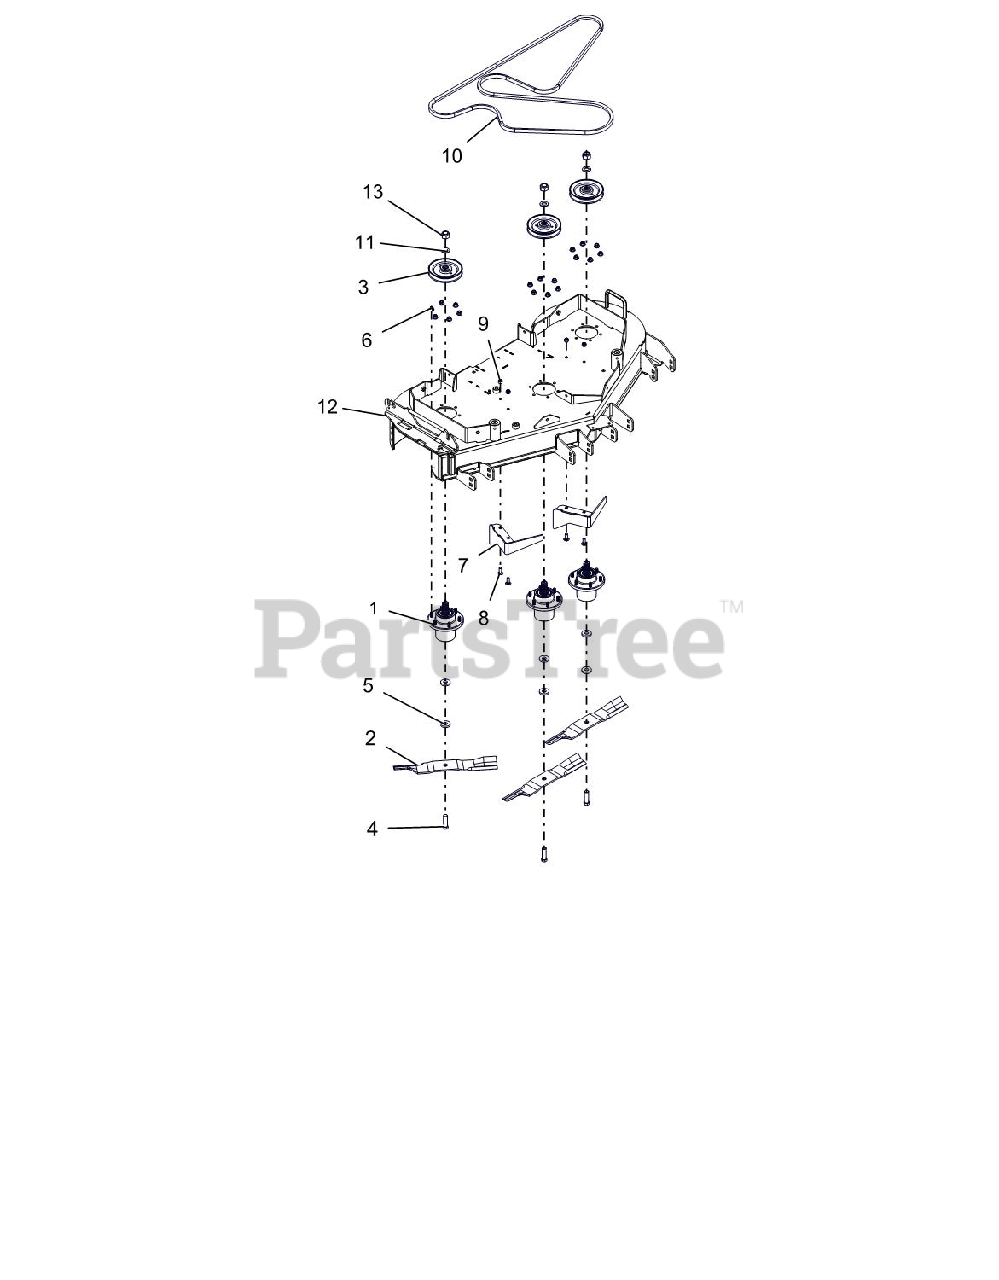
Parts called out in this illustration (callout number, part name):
1	ASSY, SPINDLE HOUSING
2	BLADE, 16.19" MOWER (HI-LIFT)
3	PULLEY, SPINDLE 5.25 X .25
4	BLT, HEX .62-11X2.00 G8 ZCC
5	WSHR,FLT .630X1.50X.25 ZCC
6	NUT,LK-NYL-FLG .38-16 G5ZC120
7	WLDMT, BAFFLE 48
8	BLT,RHSSN .38-16X1.00 G5 ZC120
9	NUT,NYL .38-16 G5 ZCC
10	BELT, B-SECTION EPDM RAW EDGE
11	WSHR-FL-STL .75X1.312X.12 ZC12
12	WLDMT, DECK 48" 2-WHEEL
13	NUT, CROWN LK .750-16 G5 ZC120
